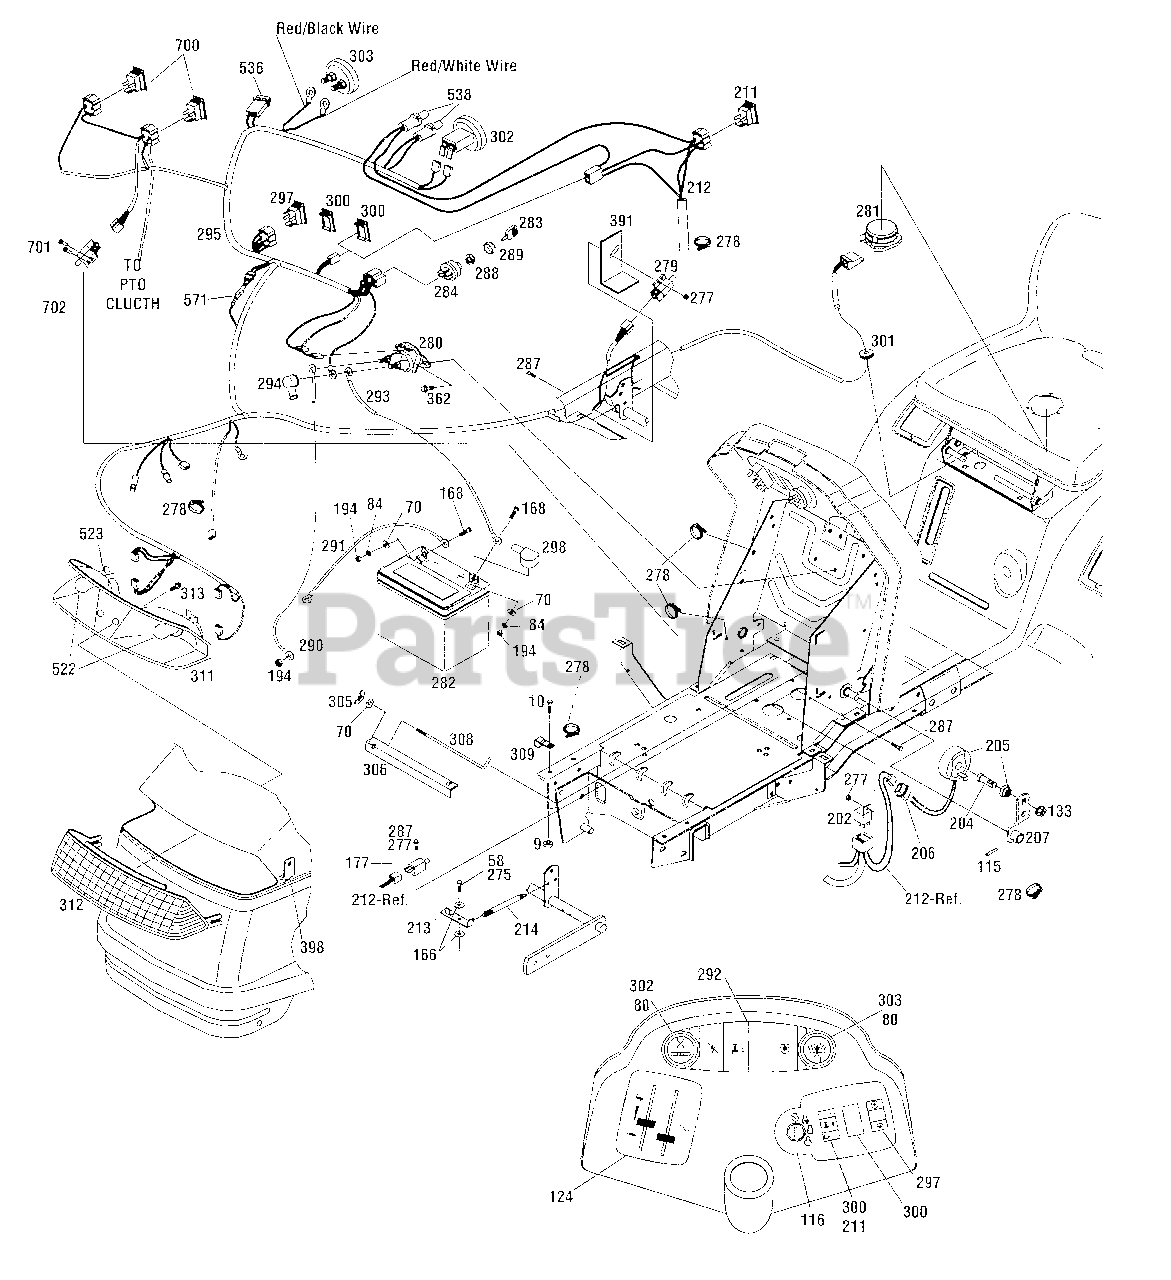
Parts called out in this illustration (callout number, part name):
9	Flange Nut, 5/16-18
10	Hex Head Screw, 5/16-18 x 3/4
58	Top Locknut, 1/4-20
70	Flat Washer, 1/4
80	Cap
84	Lockwasher, 1/4 SAE
115	Drive Pin, 3/16 x 1
116	Ignition Decal
124	Control Decal
133	Flange Nut, 7/16-20
166	Washer, 1/4 x 1-1/4
168	Hex Head Screw, 1/4-20 x 3/4
177	Push-Button Switch
194	Hex Nut, 1/4-20
202	Relay
204	Special Screw
205	Magnet
206	Housing Pin Terminal
207	Cruise Arm
211	Cruise Switch
212	Cruise Harness
213	Cruise Arm
214	Spring
275	Hex Head Screw, 1/4-20 x 5/8
277	Keps Nut, #10-24
278	Cable Tie
279	Push-Button Switch
280	Solenoid
281	Seat Switch
282	Battery
284	Ignition Switch
287	Sems Screw, #10-24 x 5/8
288	Ignition Switch Mounting Nut
289	Cap
290	Starter Cable
291	Negative Battery Cable
293	Battery Cable
294	Solenoid Boot
295	Main Harness
297	PTO Switch
298	Terminal Boot
300	Switch Cover
301	Grommet
302	Hour Meter
303	Ammeter
305	Wing Locknut,1/4-20
306	Battery Clamp
308	Hook Bolt
309	J-Clamp
311	Headlight Reflector
313	Self-Threading Screw
362	Self-Tapping Screw, 1/4-20 x 1/2
391	Switch Bracket
522	Headlight Bulb
523	Socket
536	Fuse
538	Panel Light Bulb
571	Diode
700	Relay
701	Tap Screw, #10-16 x 5/8
702	Safety Switch
